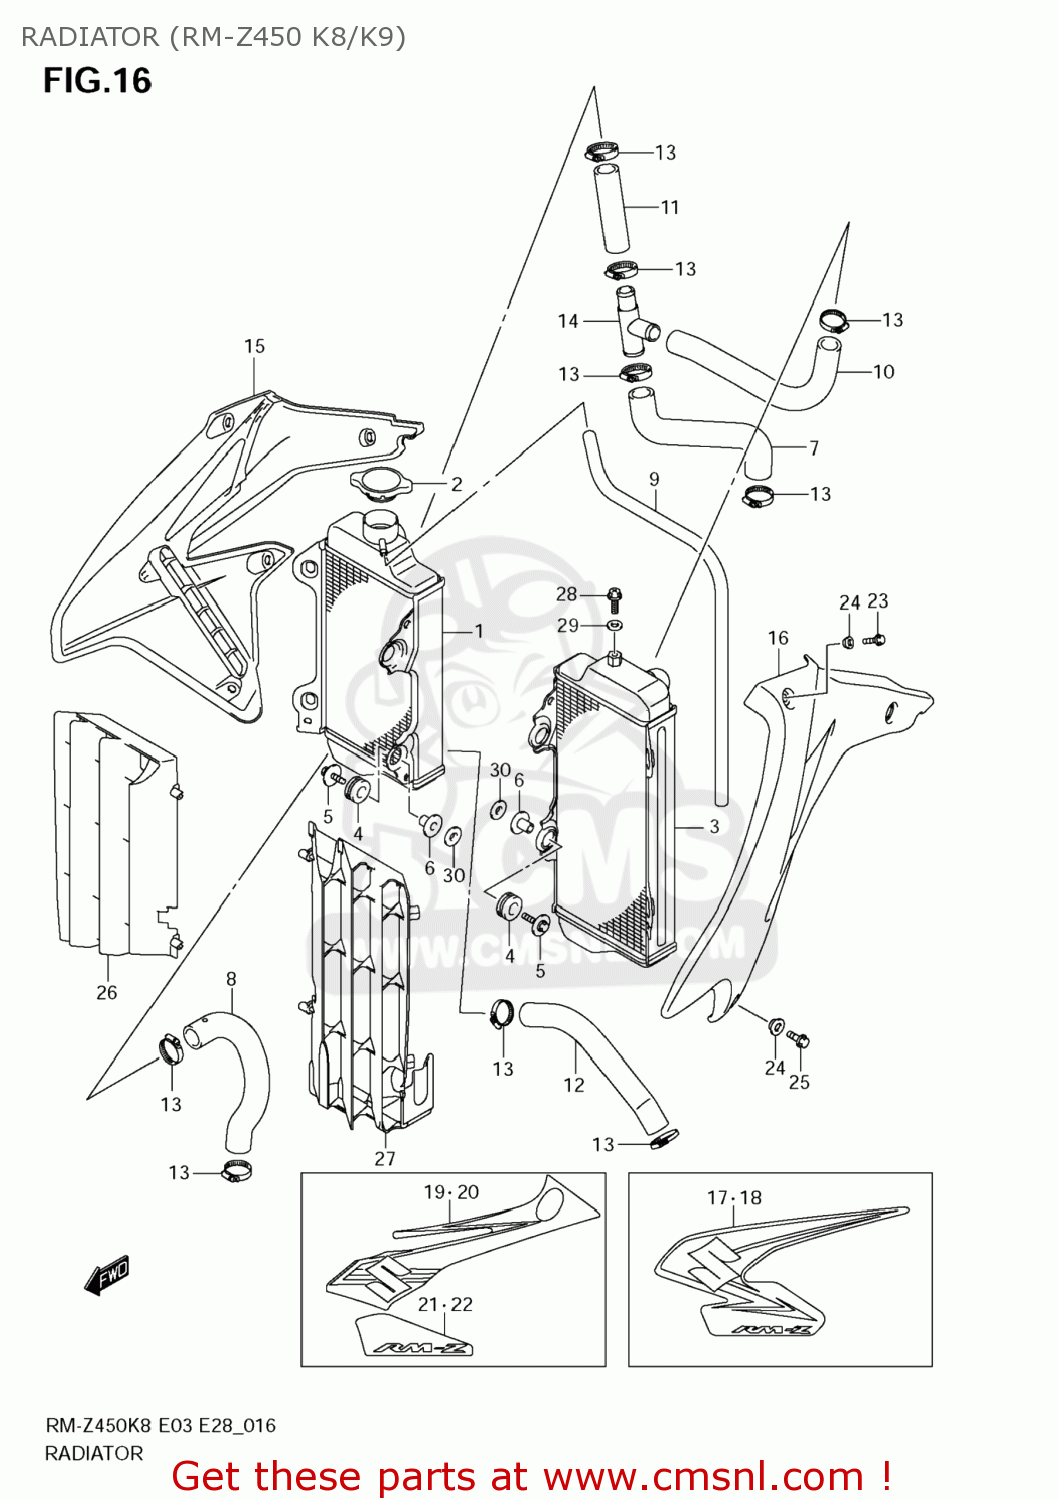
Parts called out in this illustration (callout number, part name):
1	RADIATOR,WATER
2	CAP COMP,RADIATOR
3	RADIATOR,WATER,L
4	CUSHION,RADIATOR LWR
5	BOLT(6X25)
6	SPACER(6.5X10.5X14.1)
7	HOSE,RADIATOR INLET
8	HOSE,RADIATOR OUTLET
9	HOSE(5X8X1000)
10	HOSE,RADIATOR JOINT UPR NO.1
11	HOSE,RADIATOR JOINT UPR NO.2
12	HOSE,RADIATOR JOINT LWR
13	CLAMP
14	JOINT,RADIATOR HOSE
15	COVER,RADIATOR,R
16	COVER,RADIATOR,L
17	TAPE,RADIATOR COVER,R
18	TAPE,RADIATOR COVER,L
19	TAPE,RADIATOR COVER,R
20	TAPE,RADIATOR COVER,L
21	EMBLEM,RADIATOR COVER,R
22	EMBLEM,RADIATOR COVER,L
23	BOLT(6X12)
24	WASHER
25	BOLT(6X16)
26	LOUVER,RADIATOR,R
27	LOUVER,RADIATOR,L
28	UNION BOLT,AIR VENT
29	GASKET(6.4X11.5X0.8) (NAS)
30	WASHER(6.2X24X3)
